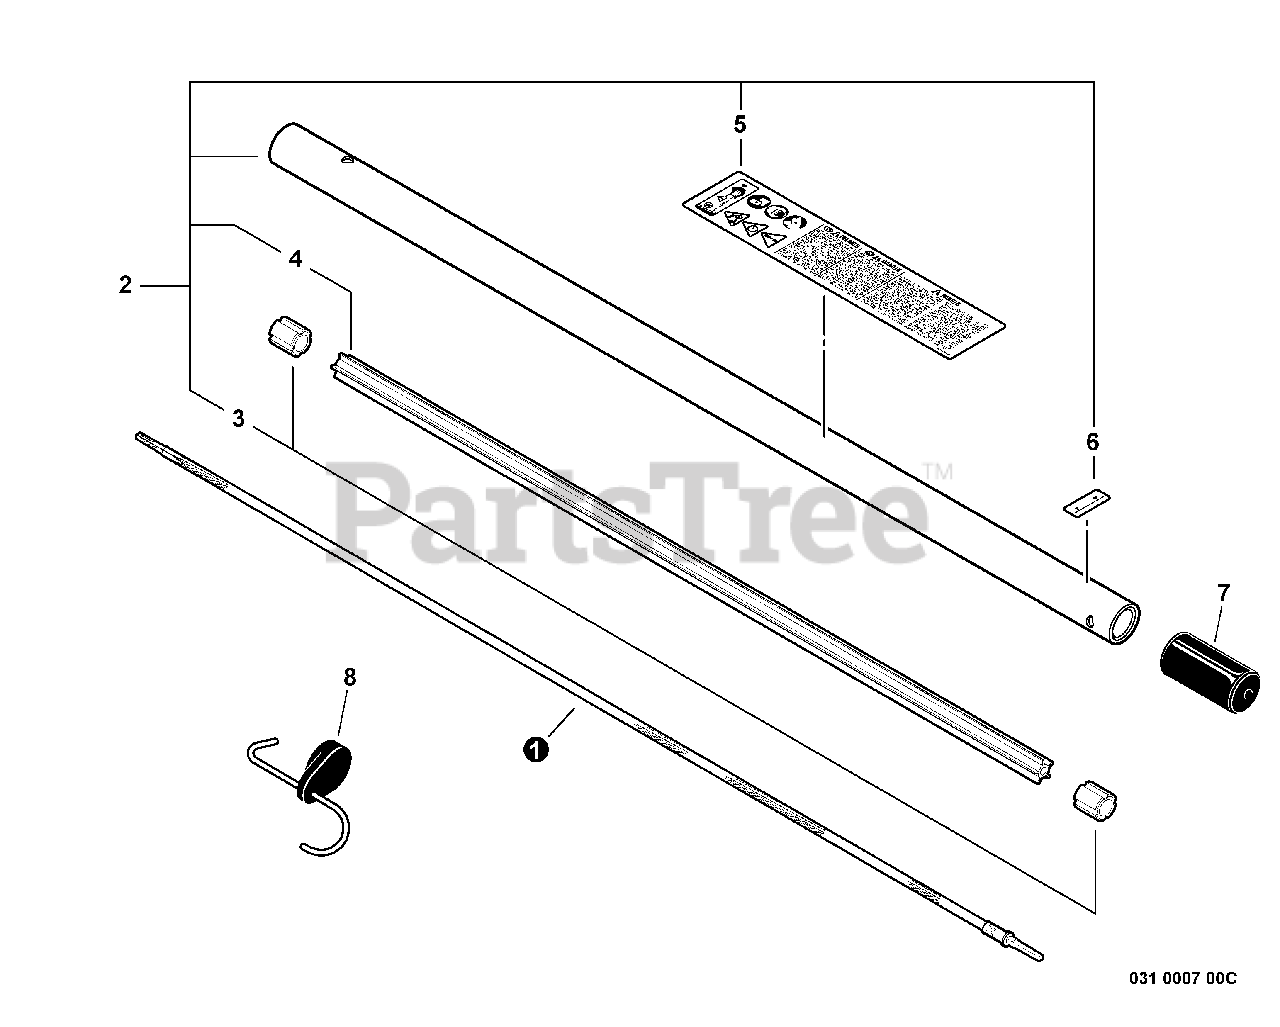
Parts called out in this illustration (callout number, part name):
1	DRIVESHAFT - FLEXIBLE
2	MAIN PIPE ASSY
4	LINER - FLEXIBLE
5	LABEL - CAUTION -- SPANISH
6	LABEL - ALIGNMENT
8	PAS ATTACHMENT HANGER
